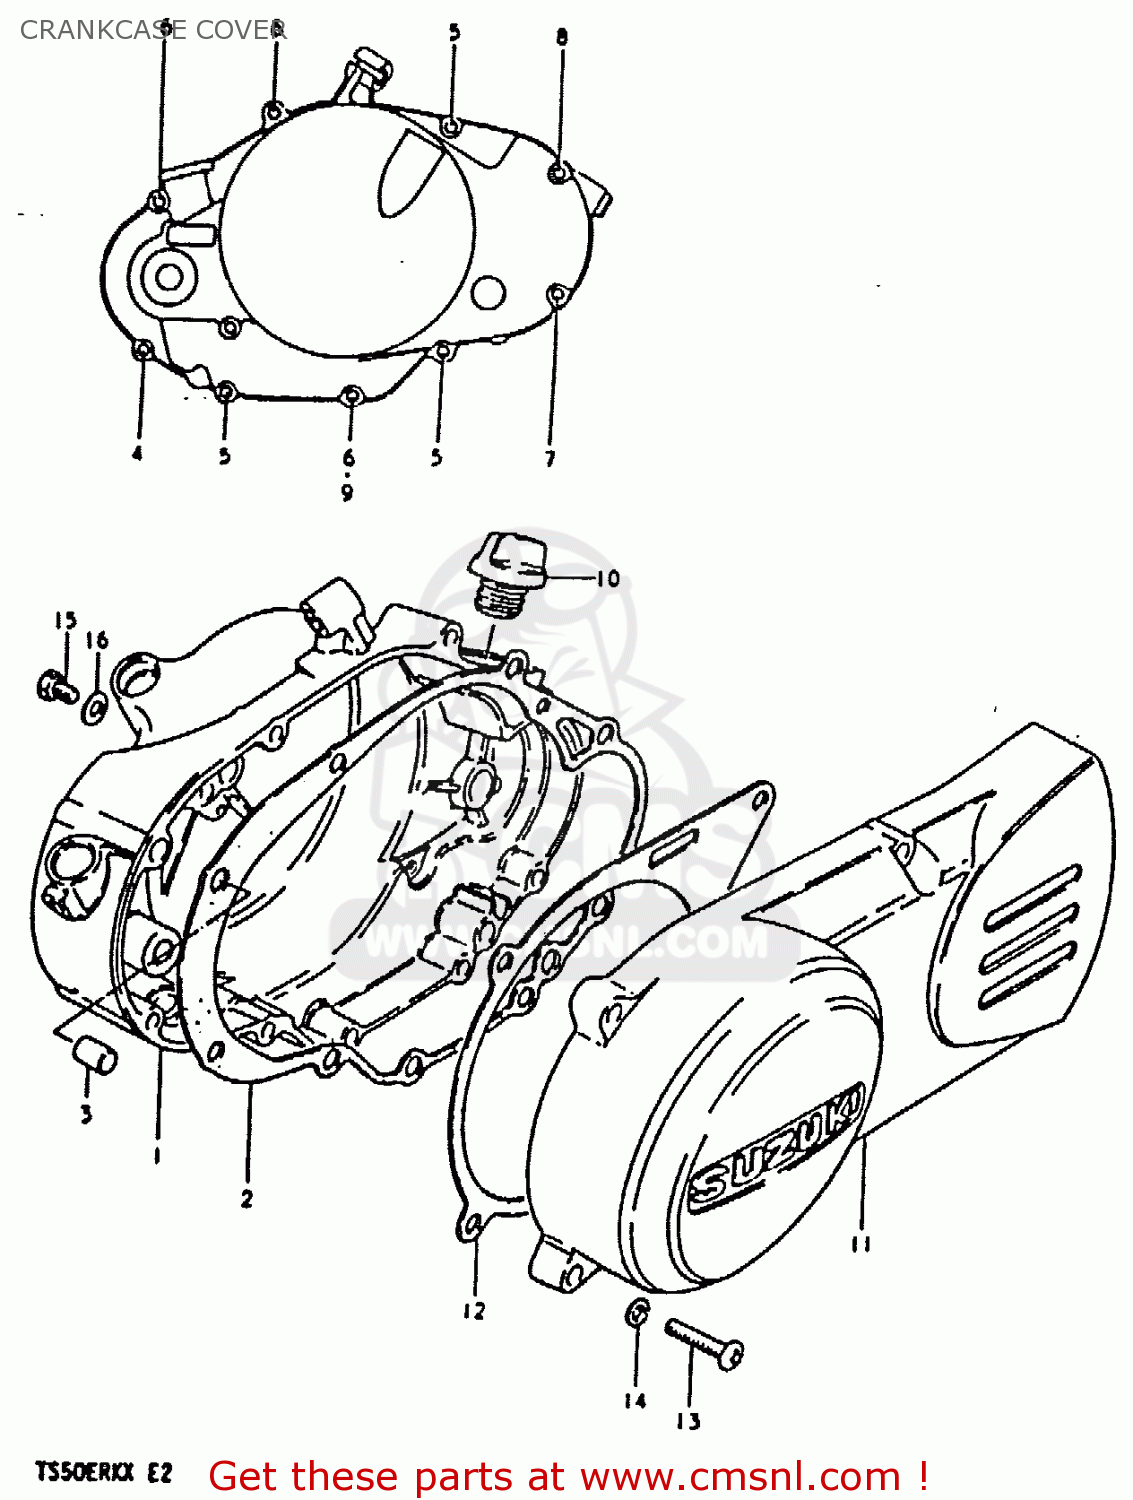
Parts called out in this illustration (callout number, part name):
1	COVER SET,CLUTCH
2	GASKET,CLUTCH COVER (MCA)
3	PIN
4	SCREW
5	SCREW 6X30
6	SCREW
7	SCREW
8	SCREW 6X60
9	GASKET(6.2X11X1).2 (NAS)
10	PLUG
11	COVER,MAGNETO
12	GASKET,MAGNETO COVER (NAS)
13	SCREW
14	WASHER
15	SCREW(6X10)
16	GASKET(6.2X11X1) (NAS)
